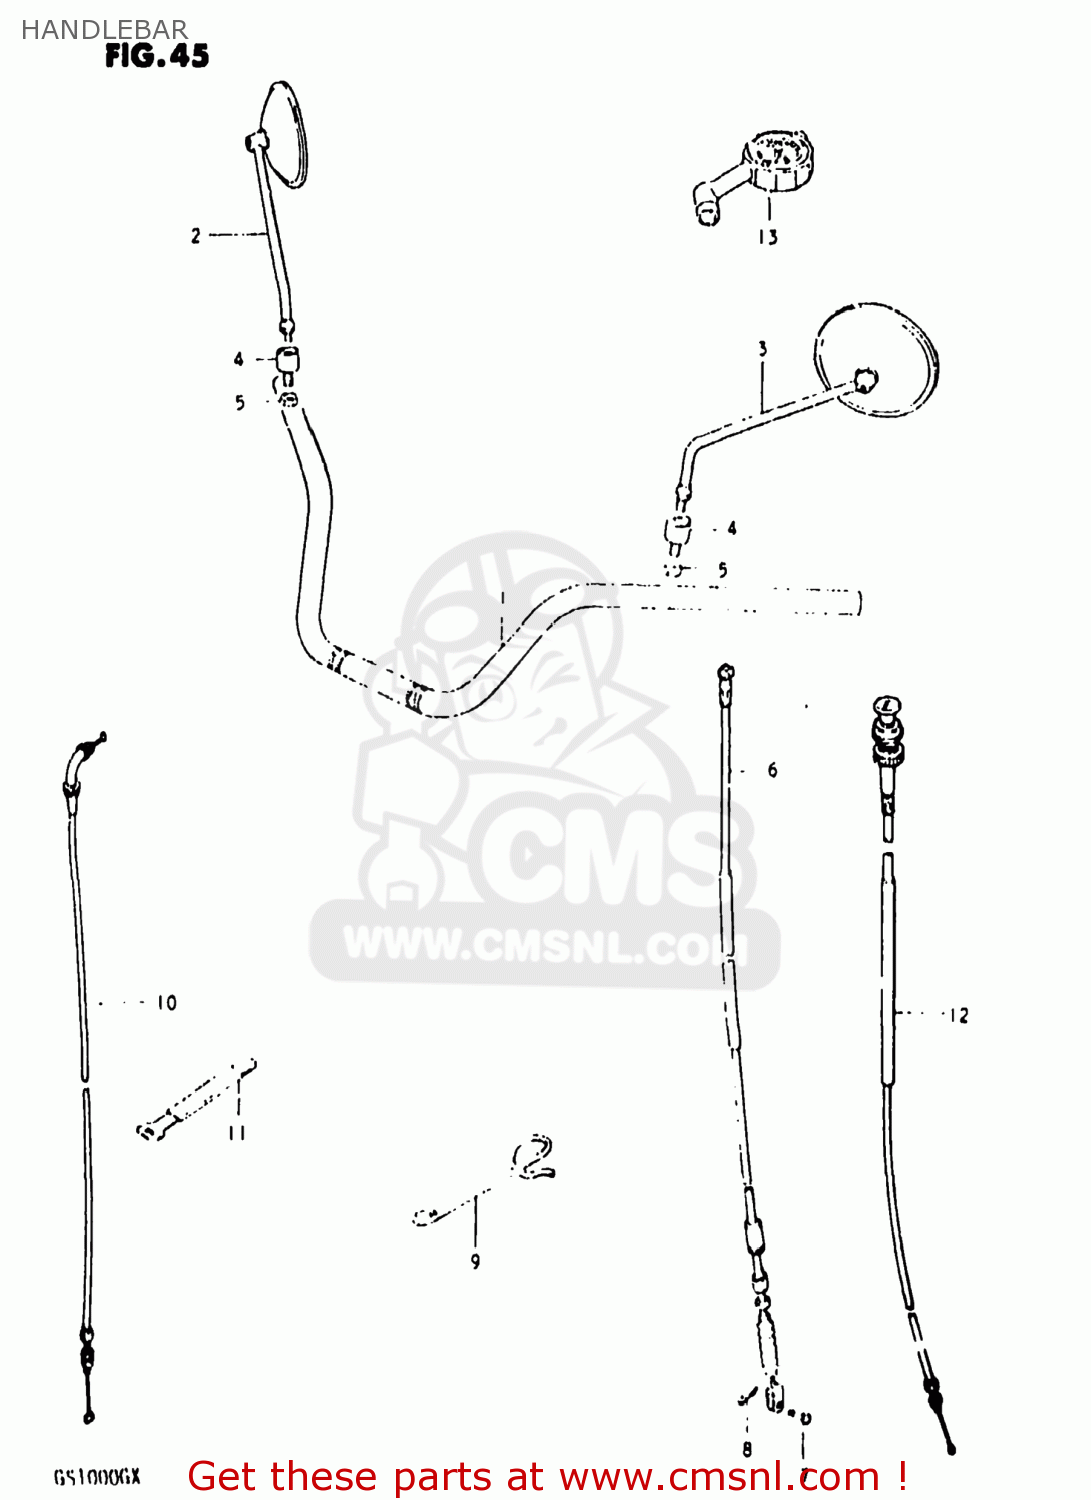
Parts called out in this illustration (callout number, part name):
1	HANDLEBAR
2	MIRROR ASSEMBLY,RIGHT
3	MIRROR ASSEMBLY,LEFT
4	CUSHION,REAR VIEW MIRROR
5	NUT
6	CABLE ASSEMBLY,CLUTCH
7	PIN(L:15)
8	PIN
9	GUIDE,CLUTCH CABLE
10	CABLE ASSEMBLY,THROTTLE
11	CLAMP
12	CABLE ASSEMBLY,STARTER
13	GAUGE ASSY,AIR PRESSURE
